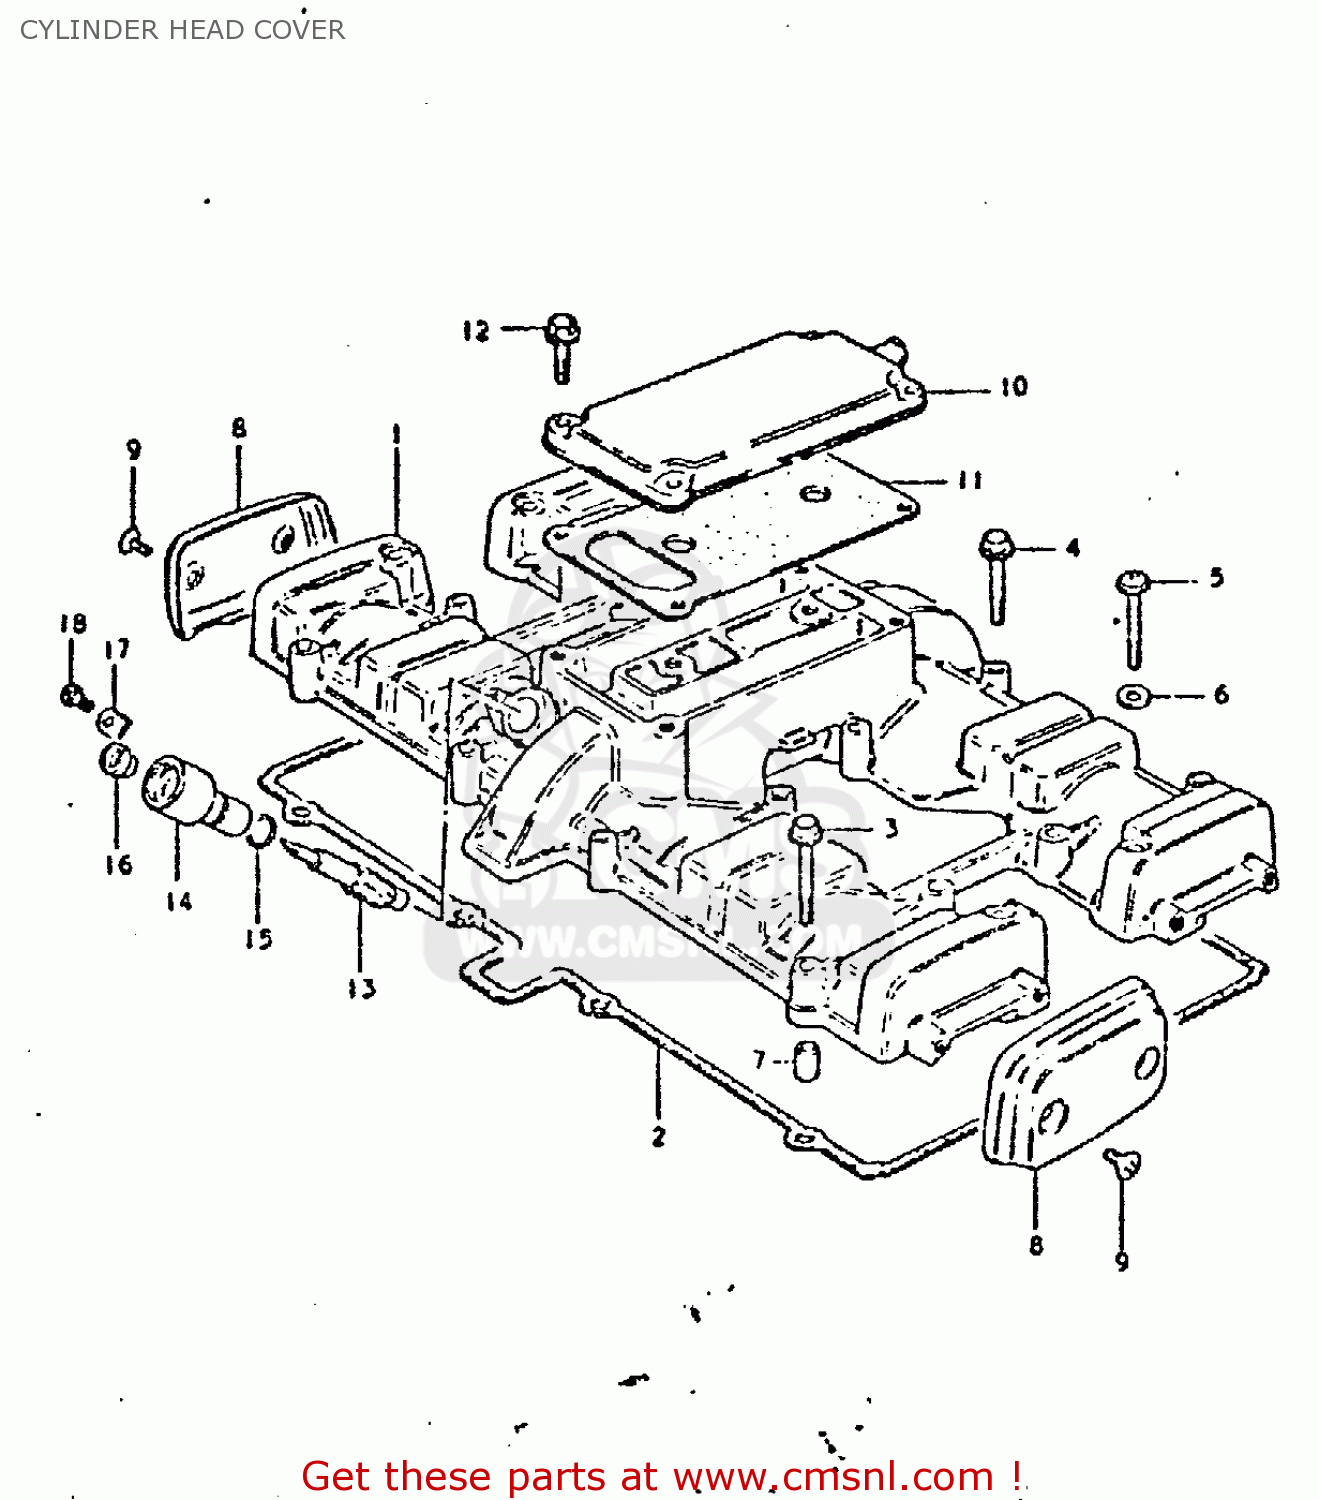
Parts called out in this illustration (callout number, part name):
1	COVER,CYLINDER HEAD
2	GASKET,CYLINDER HEAD COVER (MCA)
3	BOLT
4	BOLT 6X35
5	SCREW 6X40
6	GASKET (NAS)
7	PIN(6.2X8X11)
8	CAP,CYLINDER HEAD COVER
9	SCREW 5X12
10	COVER,BREATHER
11	GASKET (MCA)
12	BOLT,REAR
13	GEAR,TACHOMETER DRIVEN
14	SLEEVE,TACHOMETER DRIVE
15	SEAL,TACHOMETER DRIVEN
16	SEAL,OIL(5X12X8)
17	PLATE,TACH DRIVE GEAR SLEEVE
18	SCREW(5X12)
